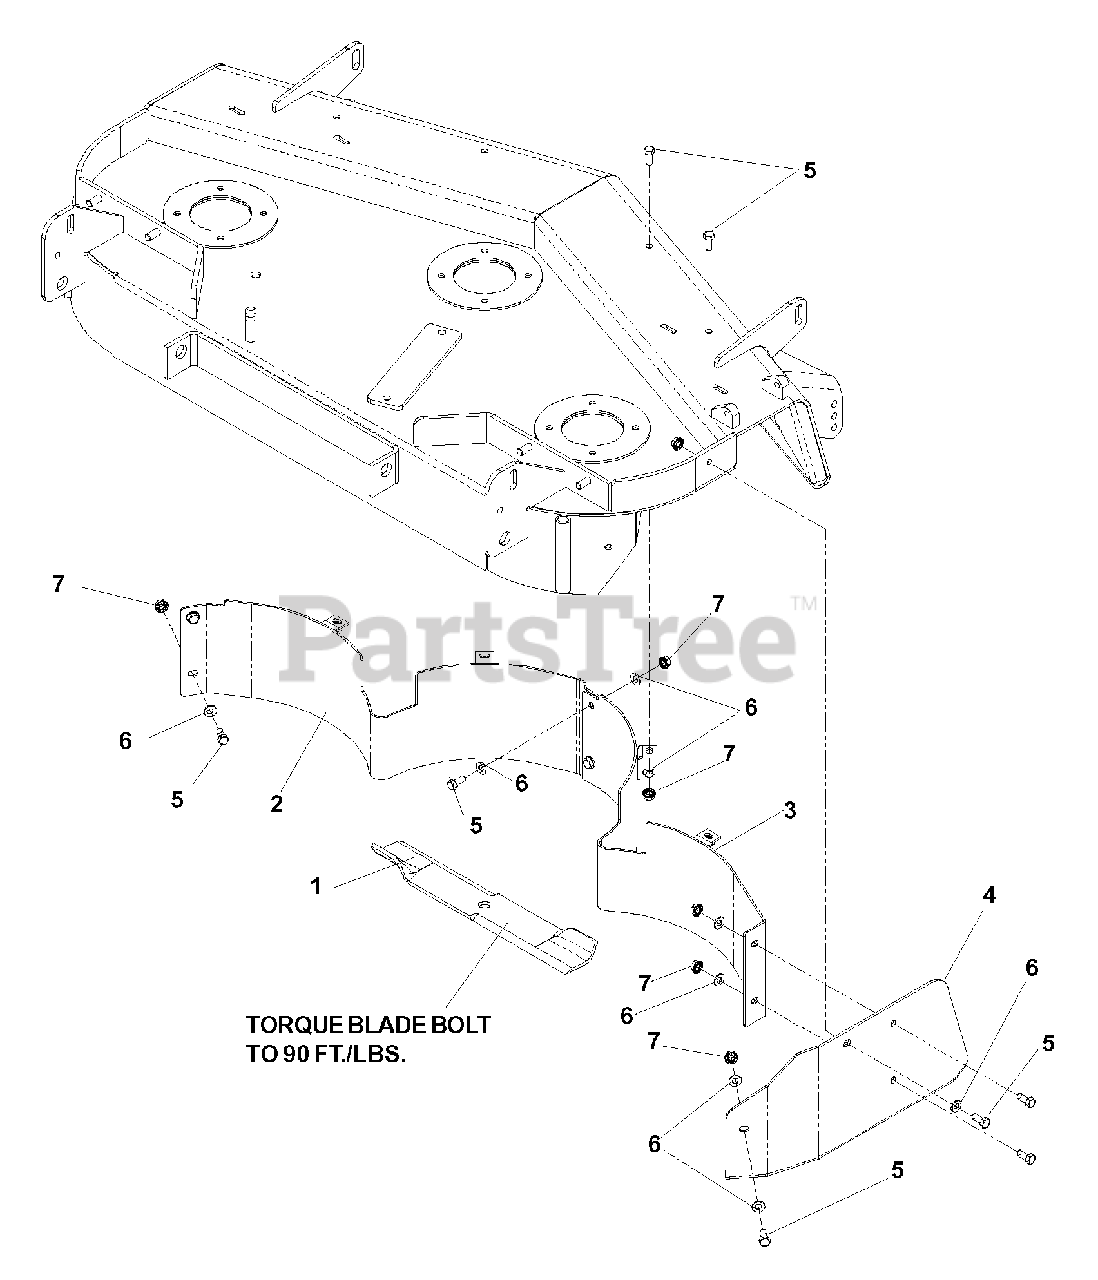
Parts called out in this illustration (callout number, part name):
1	BLADE, 21", 61" DECK
2	BAFFLE, LEFT, 61" DECK
3	BAFFLE, RIGHT, 61" DECK
4	MULCH CAP, 61" DECK
5	HCS, 5/16 -18 x 3/4,
6	WASHER, 5/16, SAE
7	NUT, 5/16 -18, WHIZLK
